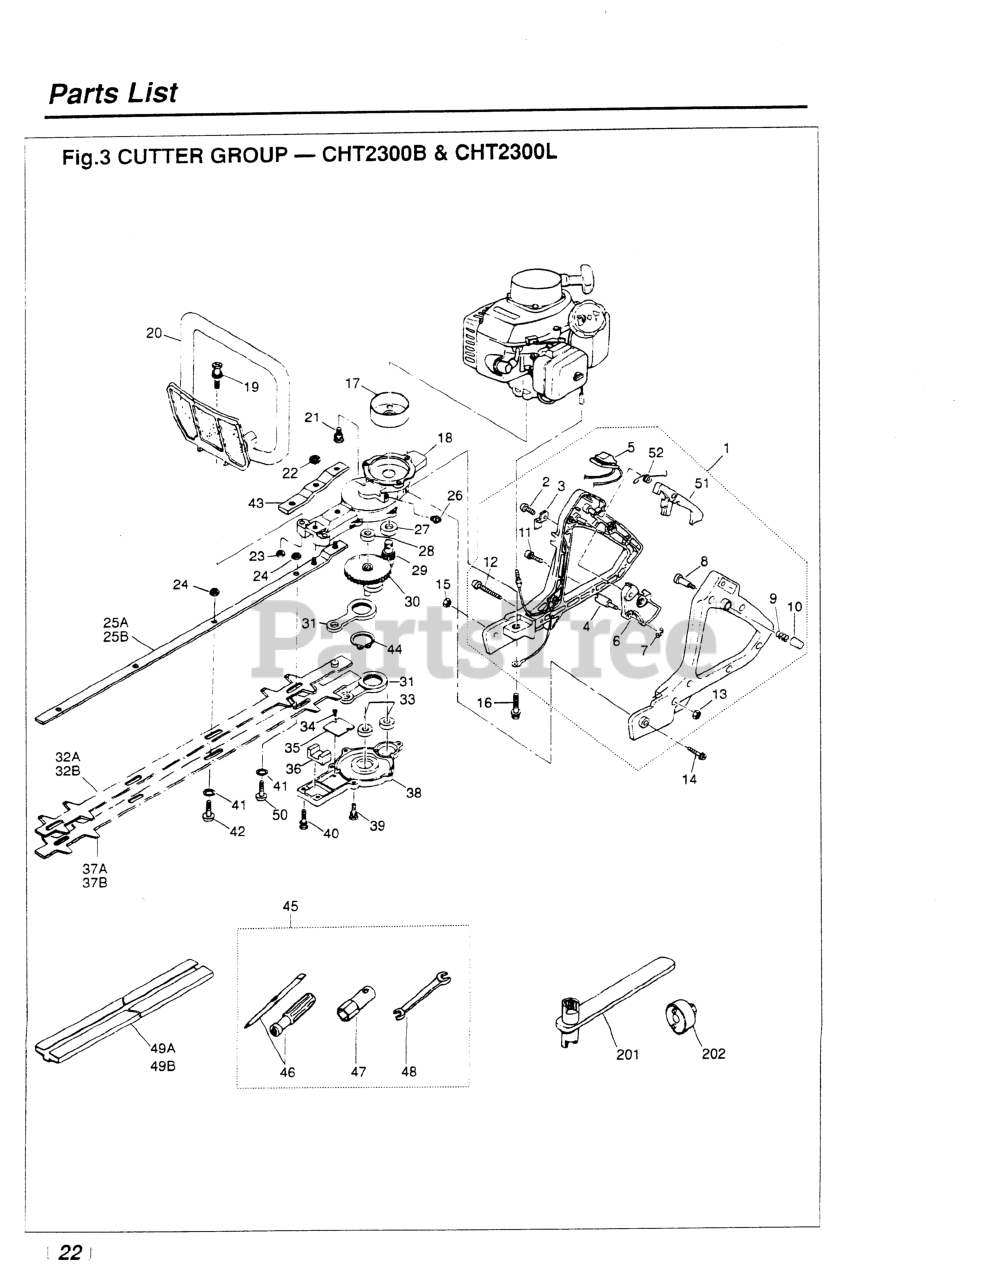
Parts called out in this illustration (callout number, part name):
1	HANDLE, REAR ASSY (RPL 3873-)
2	SCREW, M4 x 10
3	PLATE
4	END, CABLE
5	SWITCH
6	LEVER, THROTTLE (RPLS -13220)
7	RING, SNAP
9	SPRING
10	CAP, PIN
11	SCREW, M4 X 16
12	SCREW, M4 x 30
13	NUT, M6 X 4
14	BOLT, M6 X 50
15	NUT, M6 X 5
16	BOLT, M6 X 40
17	DRUM, CLUTCH
18	CASE, MIDDLE (RPLS -11110)
19	BOLT, M6x35 (RPLS -50635)
20	HANDLE (RPLS -12101)
21	BOLT, M6 X 14
22	NUT
23	NUT, M6 X 5
24	NUT, M6
25B	PLATE, GUIDE (RPLS -11611) 30
26	FITTING, GREASE
27	BEARING
28	BEARING
29	PINION
30	GEAR COMPLETE
31	ROD
32B	BLADE, UPPER DOUBLE 30
33	BEARING
34	SCREW, M3 x 5
35	PLATE
36	FELT
37B	BLADE, LOWER DOUBLE 30
38	CASE, LOWER
39	BOLT, M5 x 16
40	BOLT, M5 X 20
43	PLATE (RPLS 3880-11130)
44	RING, SNAP, M25 X 1.2
45	TOOL SET
46	SCREWDRIVER
47	SOCKET, HEX, 3/4
48	SPANNER, 8 X 10 (RPLS 2540- )
49B	COVER, BLADE (30
52	SPRING (REPLACES -13321)
202	WRENCH (TOOL)
